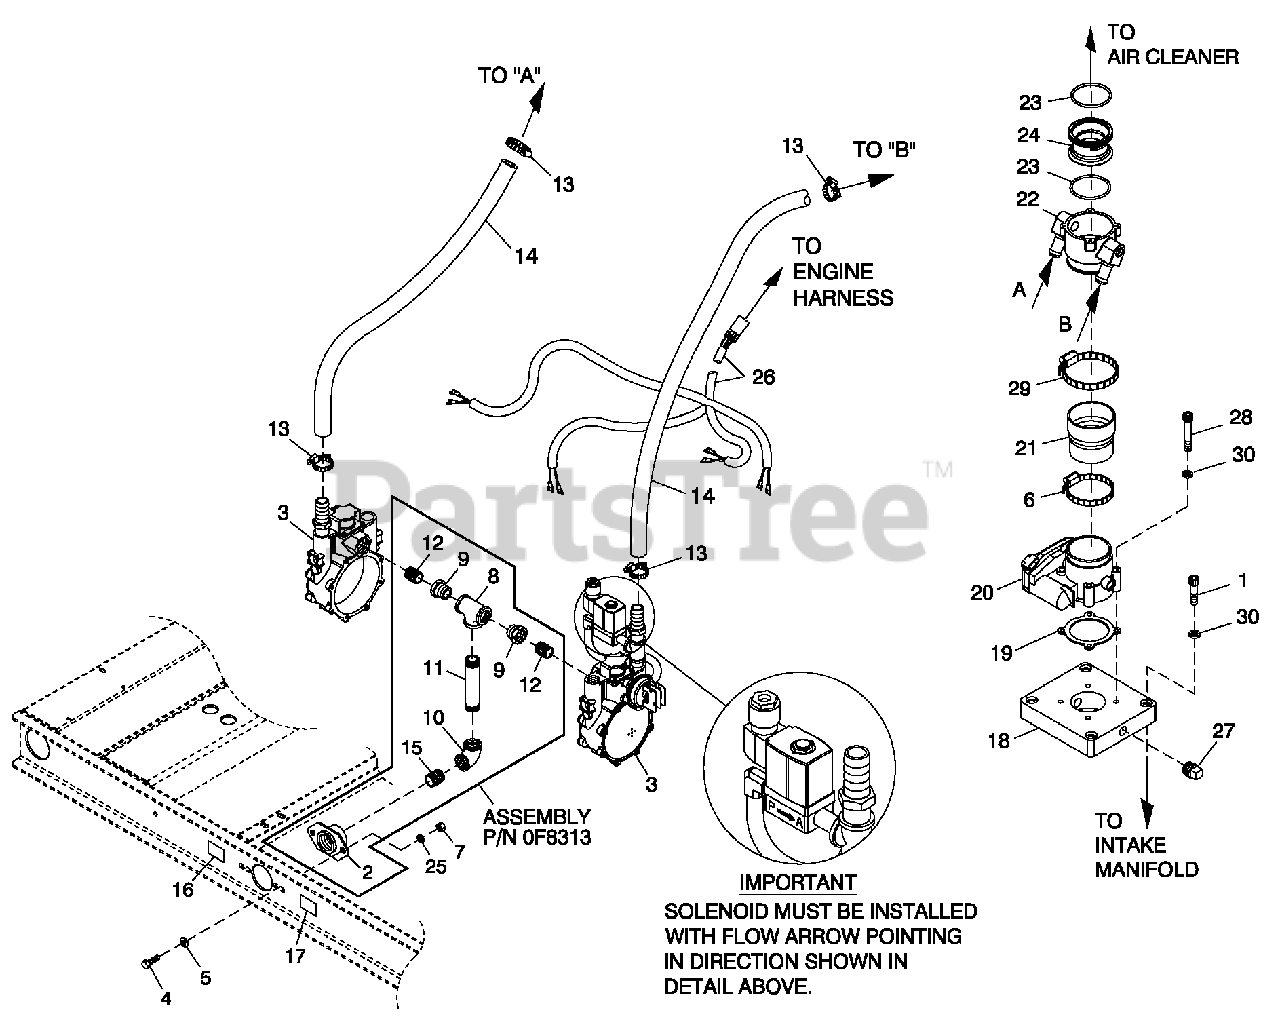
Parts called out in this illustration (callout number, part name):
1	SCREW SHC M6-1.0 X 25 G12.9 ZP
2	SUPPORT NAT GAS SOLENOID
3	REG ASSY 4.6L 80KW LPV CPL
4	SCREW HHC M12-1.75 X 20 G8.8
5	WASHER FLAT 1/2 ZINC
6	CLAMP HOSE #44 2.31-3.25
7	NUT HEX M12-1.75 G8 YEL CHR
8	PIPE TEE 1-1/4 NPT
9	BSHG RDCR HEX 1-1/4-3/4
10	ELBOW 90D 1-1/4 NPT
11	NIPPLE PIPE 1-1/4 NPT X 3
12	NIPPLE CLOSE 3/4 X 1.375
13	CLAMP HOSE #10 .56-1.06
14	HOSE 3/4 ID SAE-30R2 (40" LG)
15	NIPPLE CLOSE 1.25 NPT X 1.625
16	DECAL INLET PRESSURE
17	DECAL FUEL INLET LPG (LP VAPOR APPLICATION)
18	ADAPTER INTAKE MACHINED 4.6LPV
19	GASKET GOVERNOR ACTUATOR
20	ACTUATOR BOSCH 60 GOVERNOR
21	REDUCER 3.0" TO 2.75" TURBO
22	MIXER 40/60MM ACTUATOR ASSY
23	O-RING 2-3/4 X 3/32 X 2-15/16
24	VENTURI, THROTTLE 38MM
25	WASHER LOCK 1/2
26	HARNESS, FUEL JUMPER DUAL REG
27	PLUG STD PIPE 1/4 STEEL SQ HD
28	SCREW SHC M6-1.0 X 50 G8.8
29	CLAMP HOSE #52 2.81-3.75
30	WASHER LOCK M6-1/4
